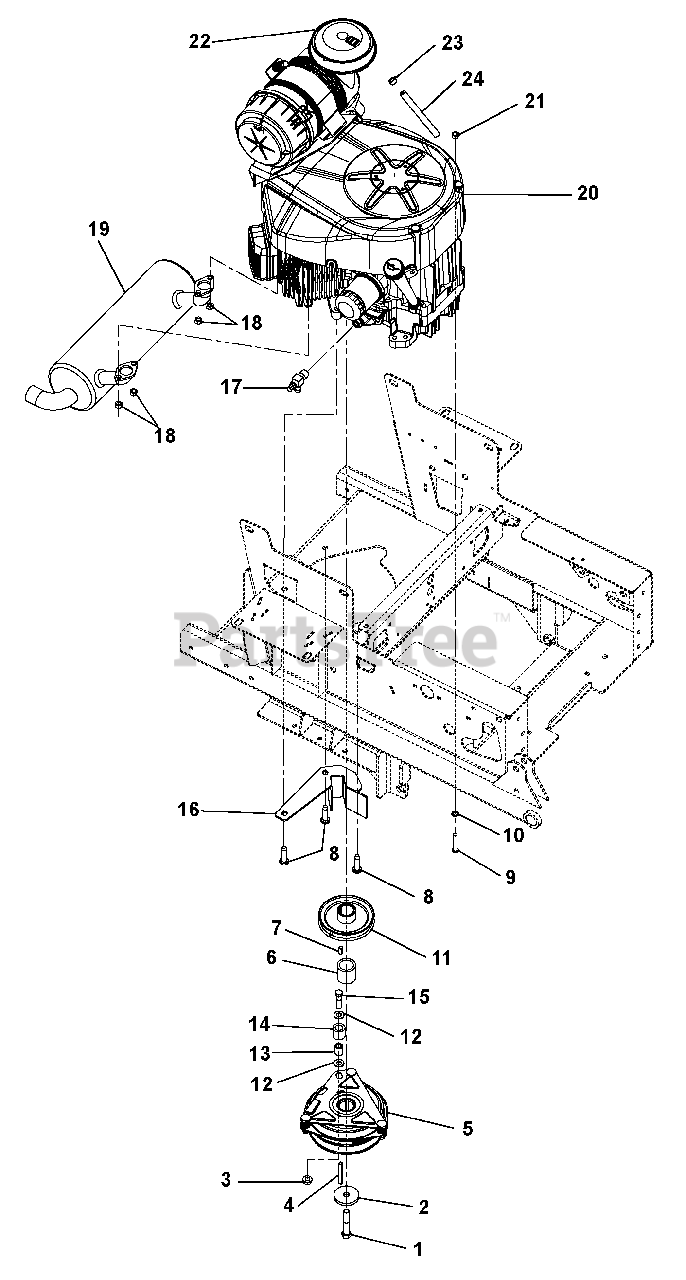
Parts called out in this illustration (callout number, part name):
1	BLT-HEX .44-20X2.50 G5 YZ EP80
2	WSHR-FL-STL .469X2.00X.25 YWZC
3	NUT-LK-TOP-FLG .38-16 YWZC
4	KEY .25X.25X2.25
5	CLUTCH, OGURA GT2.5-FE02
6	SPACER, 1.125 X 1.75 X 1.40
7	KEY-SQ .25X.625X.25 SAE 8630
8	BLT, TAP .38-16X1.5 PH TRX YZ
9	BLT-HEX .31-18X1.50 GR5 YWZC
10	WSHR-LK-EXT.326X.599X.031YWZC
11	SHEAVE, 4.831 X 1.127 ENGINE
12	WSHR-FL-STL.406X.812X.065 YWZ
13	BUSH.,S.407X.625X.813 ST
14	BUMPER,RUBBER .62X1.0X.88 LG
15	BLT-HEX .38-16X1.50 GR5 YWZC
16	100I CLUTCH STOP WMT - BLACK
17	DRAIN, 1/2" OIL
18	NUT-LK-TOP M8-1.25 YWZC
19	MUFFLER, KAW (INTERMEDIATE-Z)
20	ENGINE, 23HP KAWASAKI
21	NUT-LK-CTR .31-18 YWZC
22	CAP, AIR CLEANER INTAKE (2")
23	CLAMP, FUEL LINE
24	HOSE, .25 LOW-PERM BULK GAS
